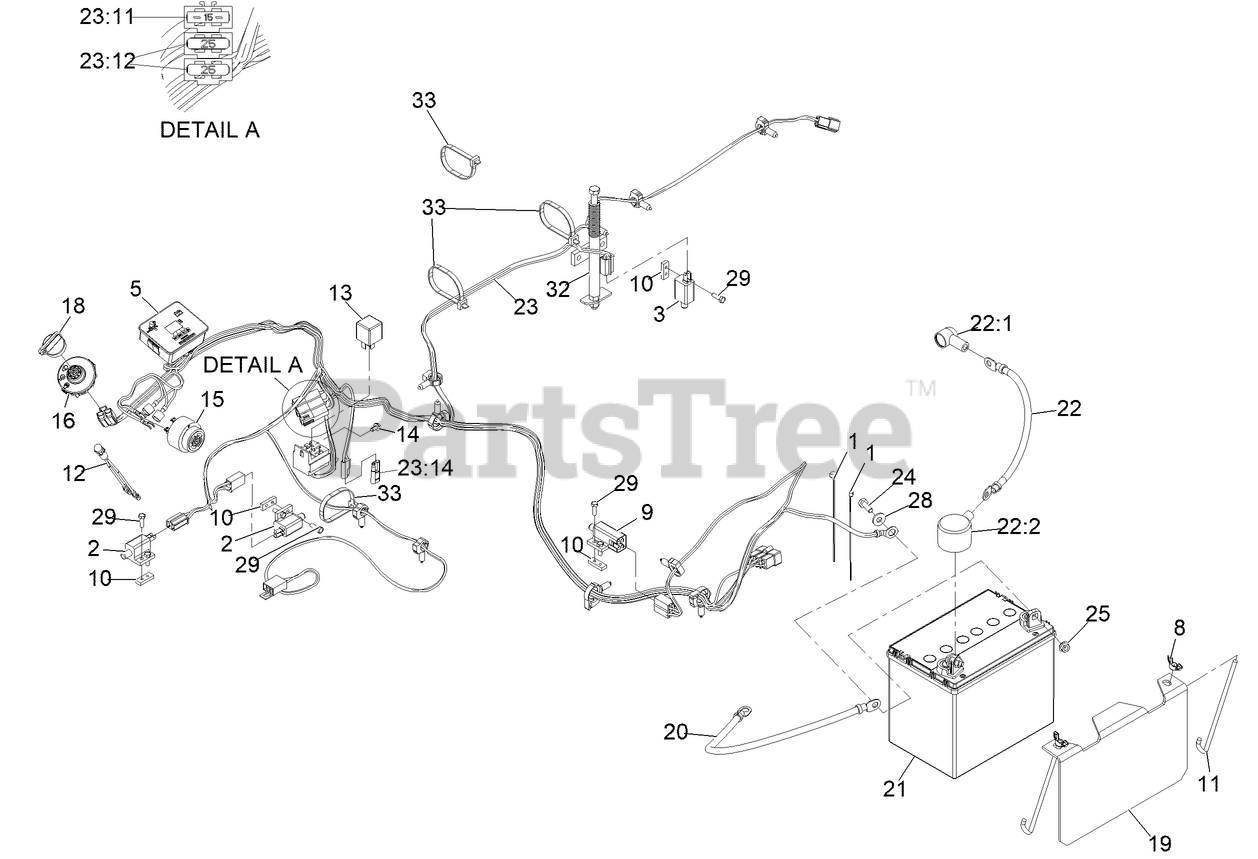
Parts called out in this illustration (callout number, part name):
1	TIE-CABLE
2	SWITCH-OPEN, NORMALLY
3	SWITCH-CLOSED, NORMALLY
5	HOUR METER ASM
8	WINGNUT
9	SWITCH
10	PLATE-TAPPED
11	BOLT-HOLDDOWN
12	INDICATOR-LED, RED
14	SCREW-HWH
15	ALARM-TONE, DUAL
16	SWITCH-IGNITION
18	KEY-IGNITION
19	HOLD DOWN-BATTERY
20	CABLE-BATTERY, NEGATIVE
21	BATTERY- WET, 12V, 300 CCA
22	CABLE-BATTERY, POSITIVE
22:1	INSULATOR-SOLENOID
22:2	INSULATOR-BATTERY
23	HARNESS-WIRING
23:11	FUSE-BLADE, 15 AMP
23:12	FUSE-BLADE, 25 AMP
23:14	CAP-PLUG
24	SCREW-HH
25	NUT-HF
28	WASHER-FLAT
32	HOPPER SWITCH ACTUATOR ASM
33	TIE-CABLE
